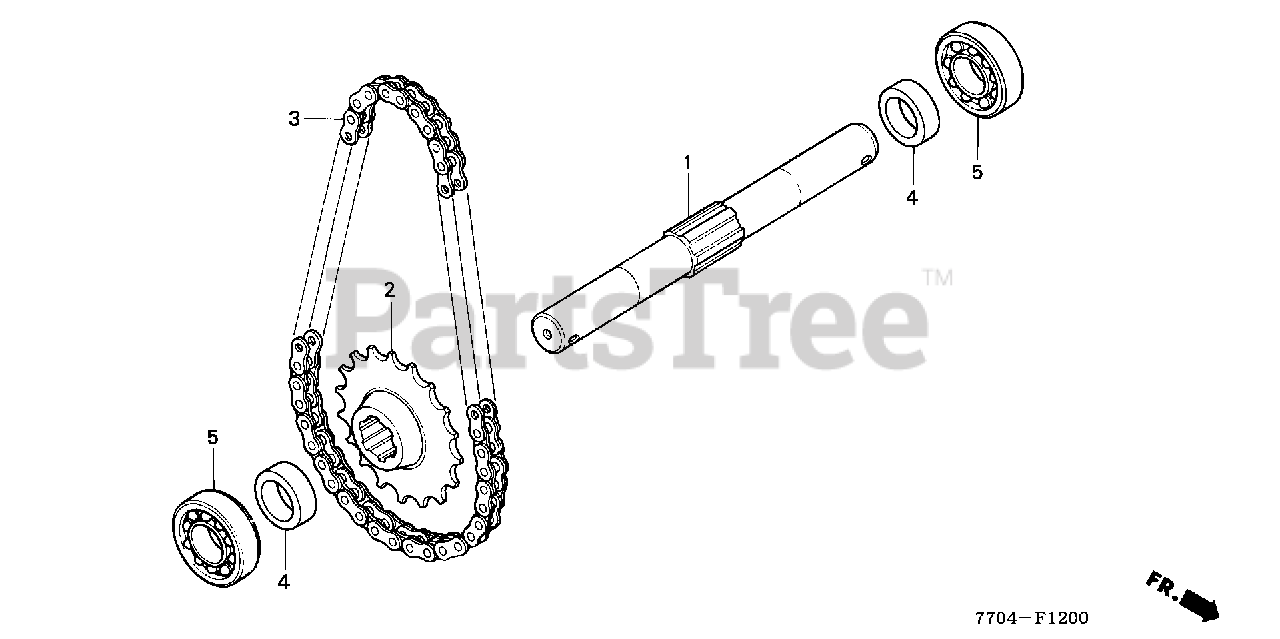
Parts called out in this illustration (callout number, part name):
1	SHAFT, WHEEL
2	SPROCKET, DRIVEN (21T)
3	CHAIN, FINAL (50)
4	COLLAR, DRIVEN SPROCKET
5	BEARING, RADIAL BALL (6205)
